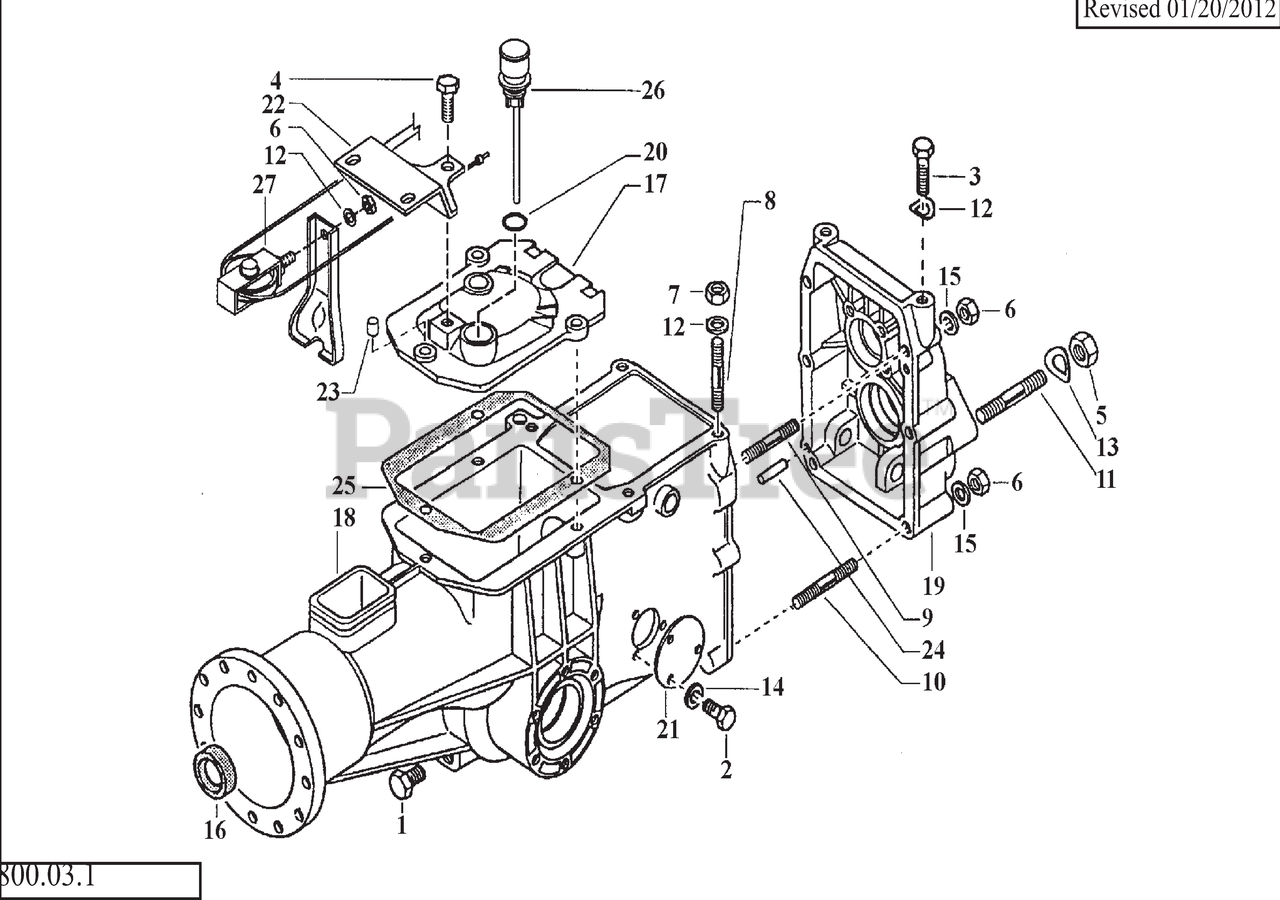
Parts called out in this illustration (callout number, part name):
1	PLUG, 1/4
2	CAP SCREW, M6X10
3	CAP SCREW, M8X20
4	CAP SCREW, M10X25
5	NUT, M12
6	NUT, LOCK, M8
7	NUT, DEFORMED LOCK, M8
8	STUD, M8X38X14X20
9	STUD, M8X58X16X16
10	STUD, M8X68X14X36
11	STUD, M64X12X1 25X26X12
12	WASHER, SUPER, M8
13	WASHER, TAPERED, M13X24X3
14	WASHER, LOCK, M6.4
15	WASHER, LOCK, M8.4
16	OIL SEAL, 15X28X6
17	COVER, GEARBOX
18	GEARBOX
19	REAR COVER
20	O-RING
21	COVER, SIDE
22	PLATE
23	SPACER, CLUTCH STOP
25	GASKET
26	CAP W/ MEASURING ROD
27	PULLEY ASSEMBLY
